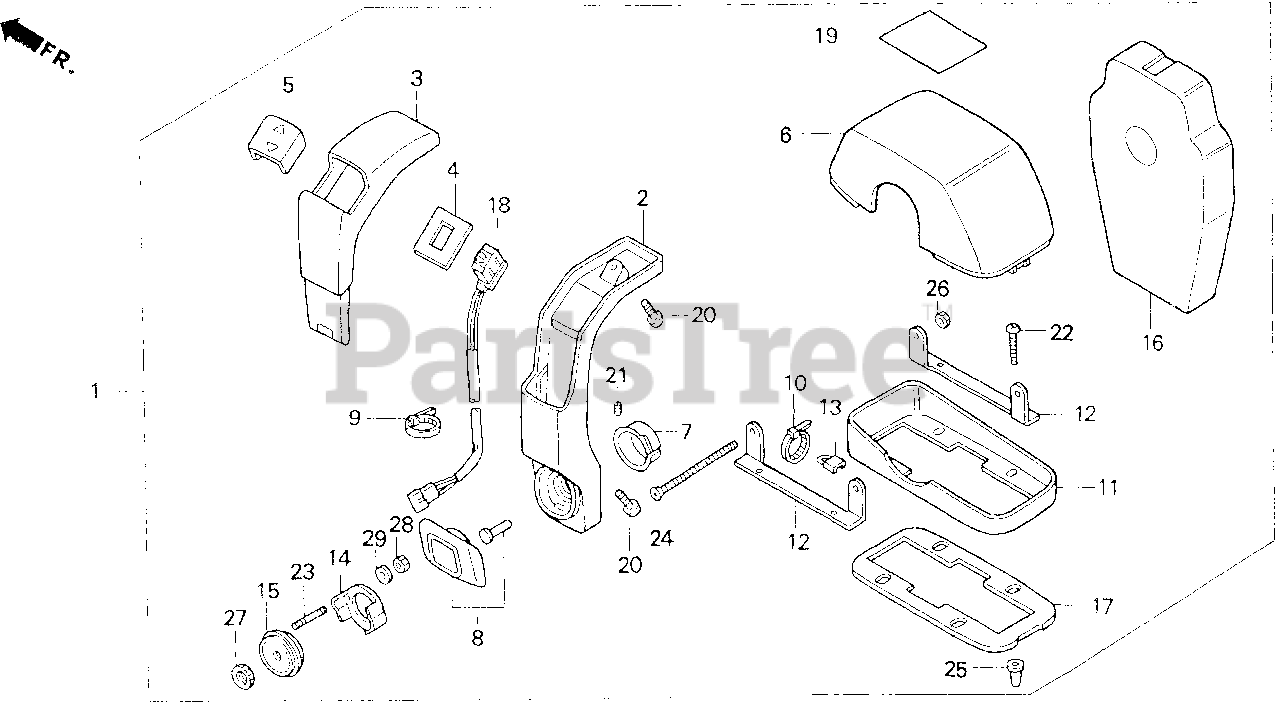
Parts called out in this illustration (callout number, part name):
1	BOX ASSY., REMOTE CONTROL (TOP MOUNT SINGLE) (NA USE ALT:24800-ZW7-V01) Use up to Frame SN 1004789.
2	HANDLE, REMOTE CONTROL Use up to Frame SN 1004789.
3	GRIP, REMOTE CONTROL HANDLE Use up to Frame SN 1004789.
4	PLATE, SWITCH SETTING Use up to Frame SN 1004789.
5	COVER, GRIP Use up to Frame SN 1004789.
6	HOUSING ASSY., REMOTE CONTROL BOX (A) (NOT AVAILABLE) Use up to Frame SN 1004789.
7	BUSHING Use up to Frame SN 1004789.
8	BUTTON ASSY. Use up to Frame SN 1004789.
9	BAND A, CABLE Use up to Frame SN 1004789.
10	BAND B, CABLE Use up to Frame SN 1004789.
11	HOUSING ASSY., REMOTE CONTROL BOX (B) Use up to Frame SN 1004789.
12	BRACKET, REMOTE CONTROL HOUSING Use up to Frame SN 1004789.
13	ANCHOR Use up to Frame SN 1004789.
14	BRACKET, SWITCH MOUNTING Use up to Frame SN 1004789.
15	PLATE ASSY., SWITCH MOUNTING Use up to Frame SN 1004789.
16	HOUSING ASSY. (INNER) (TOP MOUNT) Use up to Frame SN 1004789.
17	GASKET Use up to Frame SN 1004789.
18	SWITCH ASSY., POWER TRIM-TILT (A) Use up to Frame SN 1004789.
19	MARK, REMOTE CONTROL (SINGLE) Use up to Frame SN 1004789.
20	SCREW (10-32X1") Use up to Frame SN 1004789.
21	SCREW SET (1/4-20X16") Use up to Frame SN 1004789.
22	SCREW (10-32X1-1/2") Use up to Frame SN 1004789.
23	STUD (10-32X2") Use up to Frame SN 1004789.
24	SCREW (10-32X2-1/4") Use up to Frame SN 1004789.
25	NUT, WELDING (10-32) Use up to Frame SN 1004789.
26	NUT (10-32) Use up to Frame SN 1004789.
27	NUT, LOCK (15/32-32) Use up to Frame SN 1004789.
28	NUT (10-32) Use up to Frame SN 1004789.
29	WASHER Use up to Frame SN 1004789.
